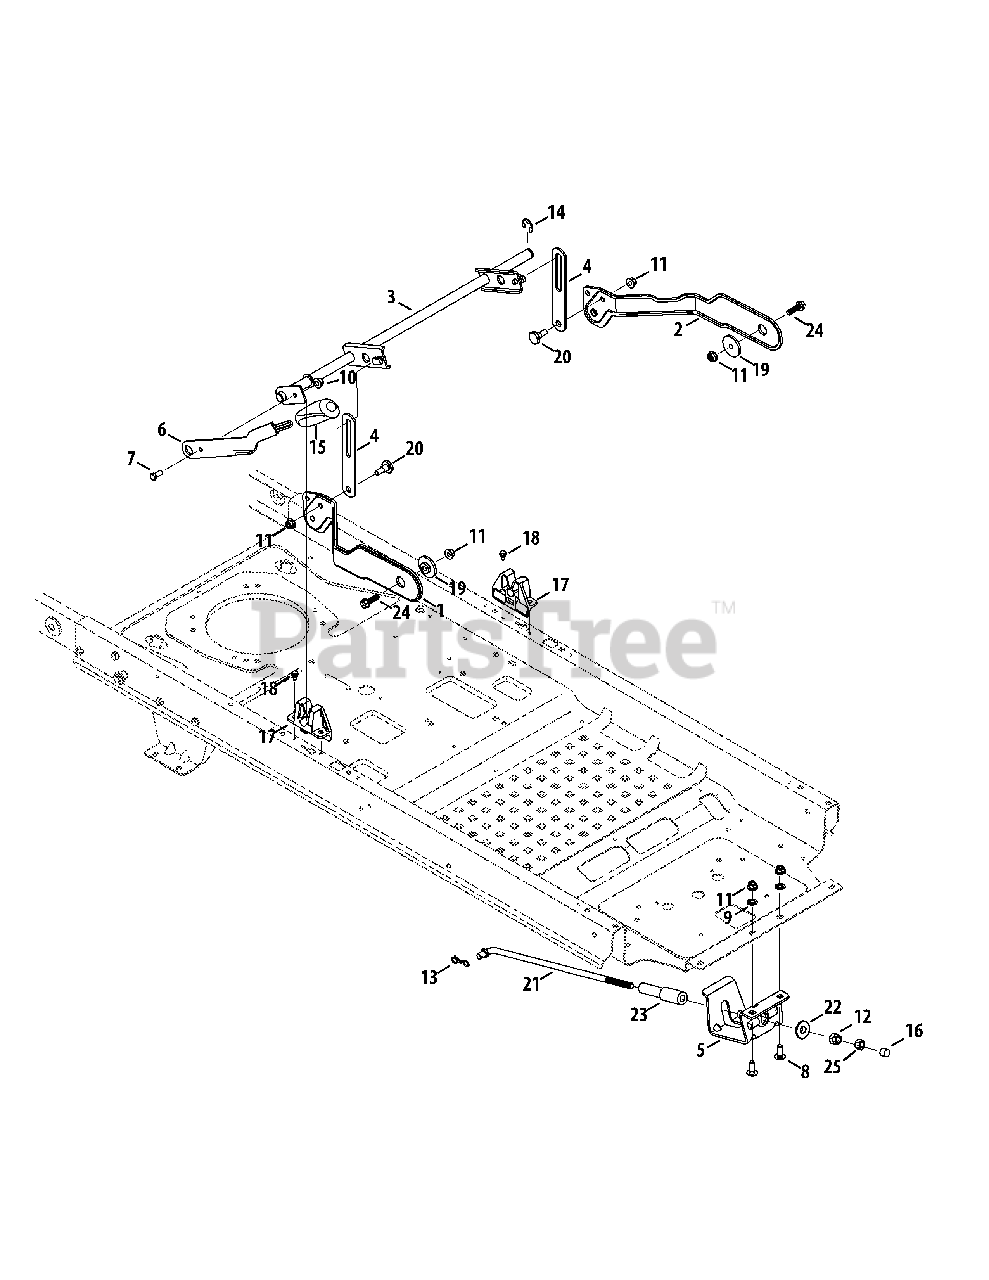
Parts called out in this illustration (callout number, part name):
1	Deck Lift Plate, RH
2	Deck Lift Plate, LH
3	Deck Lift Shift Assembly
4	Lift Link Plate
5	Rod Support Mounting Bracket
6	Deck Lift Handle
7	Hex Cap Screw, 5/16-18 x .75
8	Carriage Bolt, 3/8-16 x 1.00
9	Push Nut, 3/8
10	Flange Lock Nut, 5/16-18
11	Flange Lock Nut, 3/8-16
12	Hex Nut, 1/2-13
13	Bow-Tie Cotter Pin
14	E-Type Ring, .750
15	Grip, .50 ID
16	End Cap
17	Deck Lift Bracket
18	Shoulder Screw, .500 x 1/4-20
19	Shoulder Spacer, .854 x .232
20	Shoulder Screw, .500 Dia. x .434
21	Deck Lift Rod
22	Deck Lift pivot Cup
23	Nylon Sleeve, .55 ID x 4.50 LG
24	Screw, 3/8-16 x 1.00
25	Nut, Jam, 1/2-13
